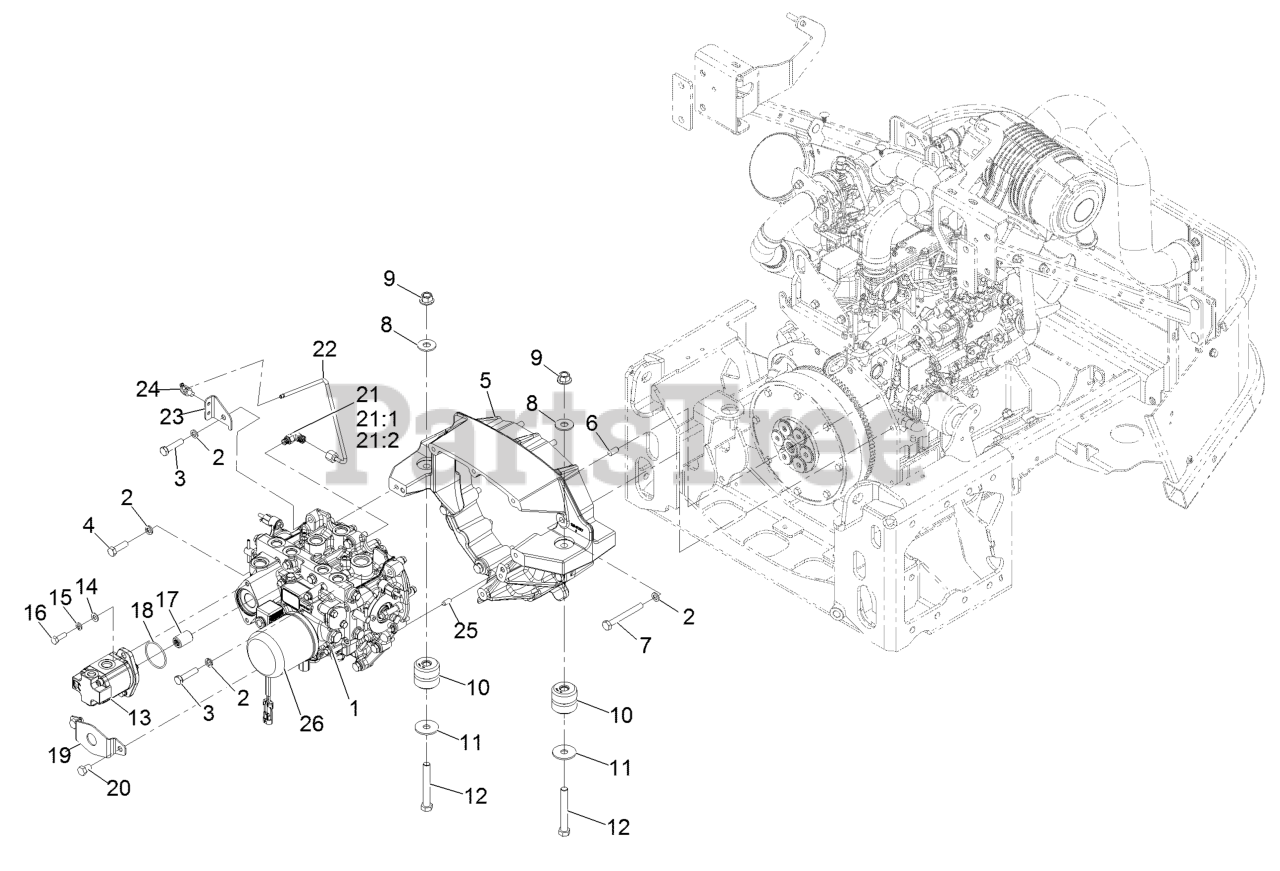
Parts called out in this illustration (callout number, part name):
1	Transmisson ASM
2	Washer-Lock
3	Screw-HH
4	Screw-HH M10-1.5 X 25Mm
5	Housing-Flywheel
6	Pin-Dowel
7	Screw-HH
8	Washer
9	Nut-Lock 1/2-13
10	Mount-Isolator
12	Screw-HH
13	HYD Gear Pump ASM
14	Washer-5/16 SAE
15	Washer-Lock 5/16
16	Screw-HH M8-1.25 X 25Mm
17	Coupler-Spline
19	Shield-Seal
20	Screw-HH
21	Fitting-Elbow, 90
21:1	O-Ring
21:2	O-Ring
22	Tube ASM
23	Support-Tube
24	Clip-Tie
25	Pin-Dowel
26	Filter-Oil, HYD
